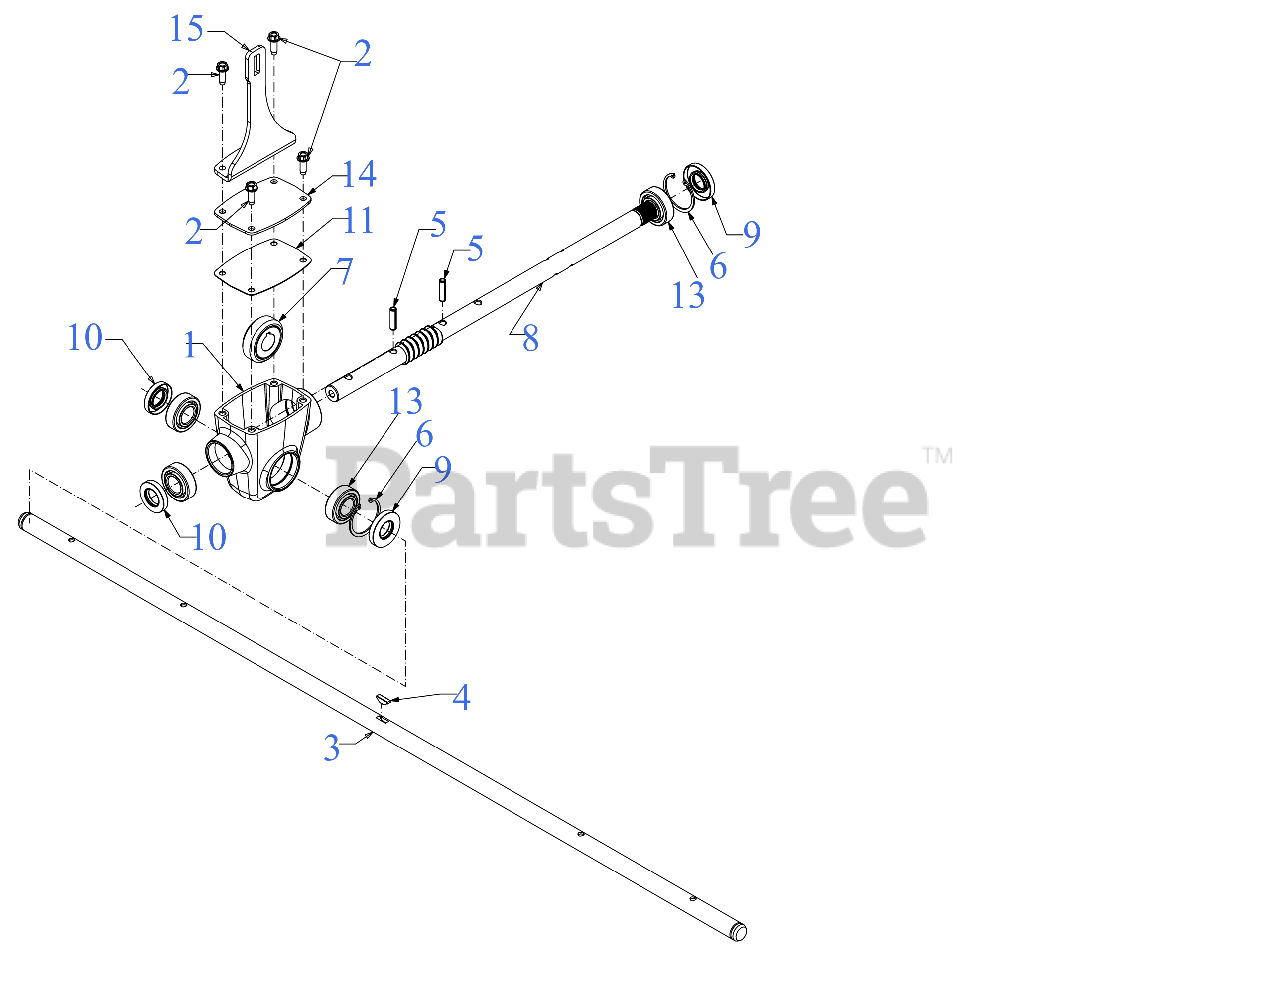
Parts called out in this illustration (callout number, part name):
1	AUGER HOUSING GEARBOX
2	SCREW 1/4-20 x .750
3	AUGER AXLE
4	KEY 3/16 x 5/8 HI-PRO
7	WORM GEAR 20T
8	WORM SHAFT
11	GEARBOX COVER GASKET
13	BALL BEARING
14	GEARBOX COVER
